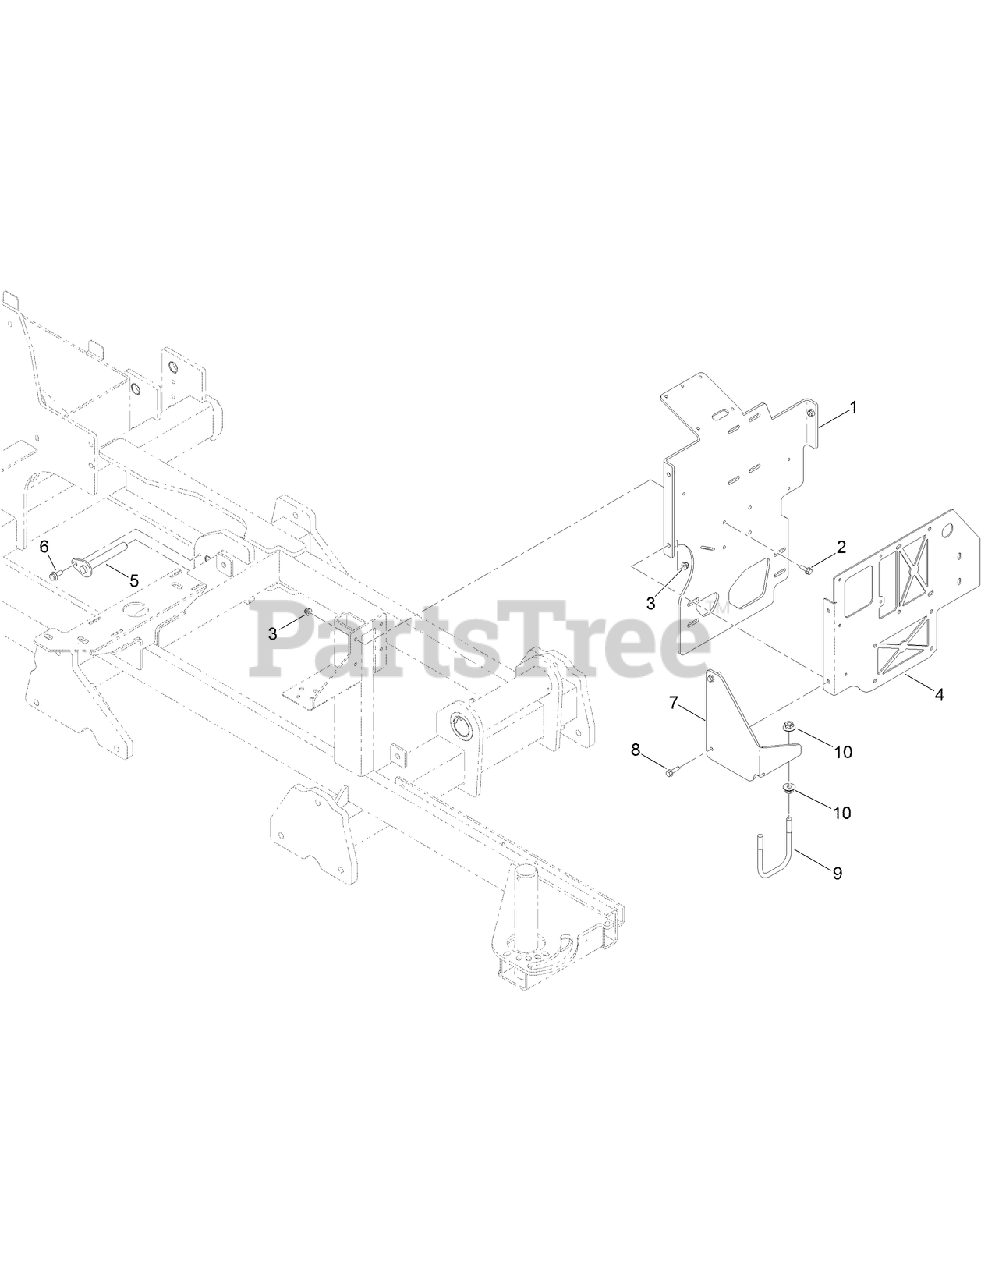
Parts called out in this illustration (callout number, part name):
1	PLATE-MOUNT, FUSE BOX
2	SCREW-HHF
3	NUT-LOCK, HHF
4	PLATE-MOUNTING, ELECTRICAL
5	PIN-FLAGGED
6	SCREW-HHF
7	SUPPORT-HOSE
8	SCREW-HHF
9	U-Bolt
10	NUT-HF
